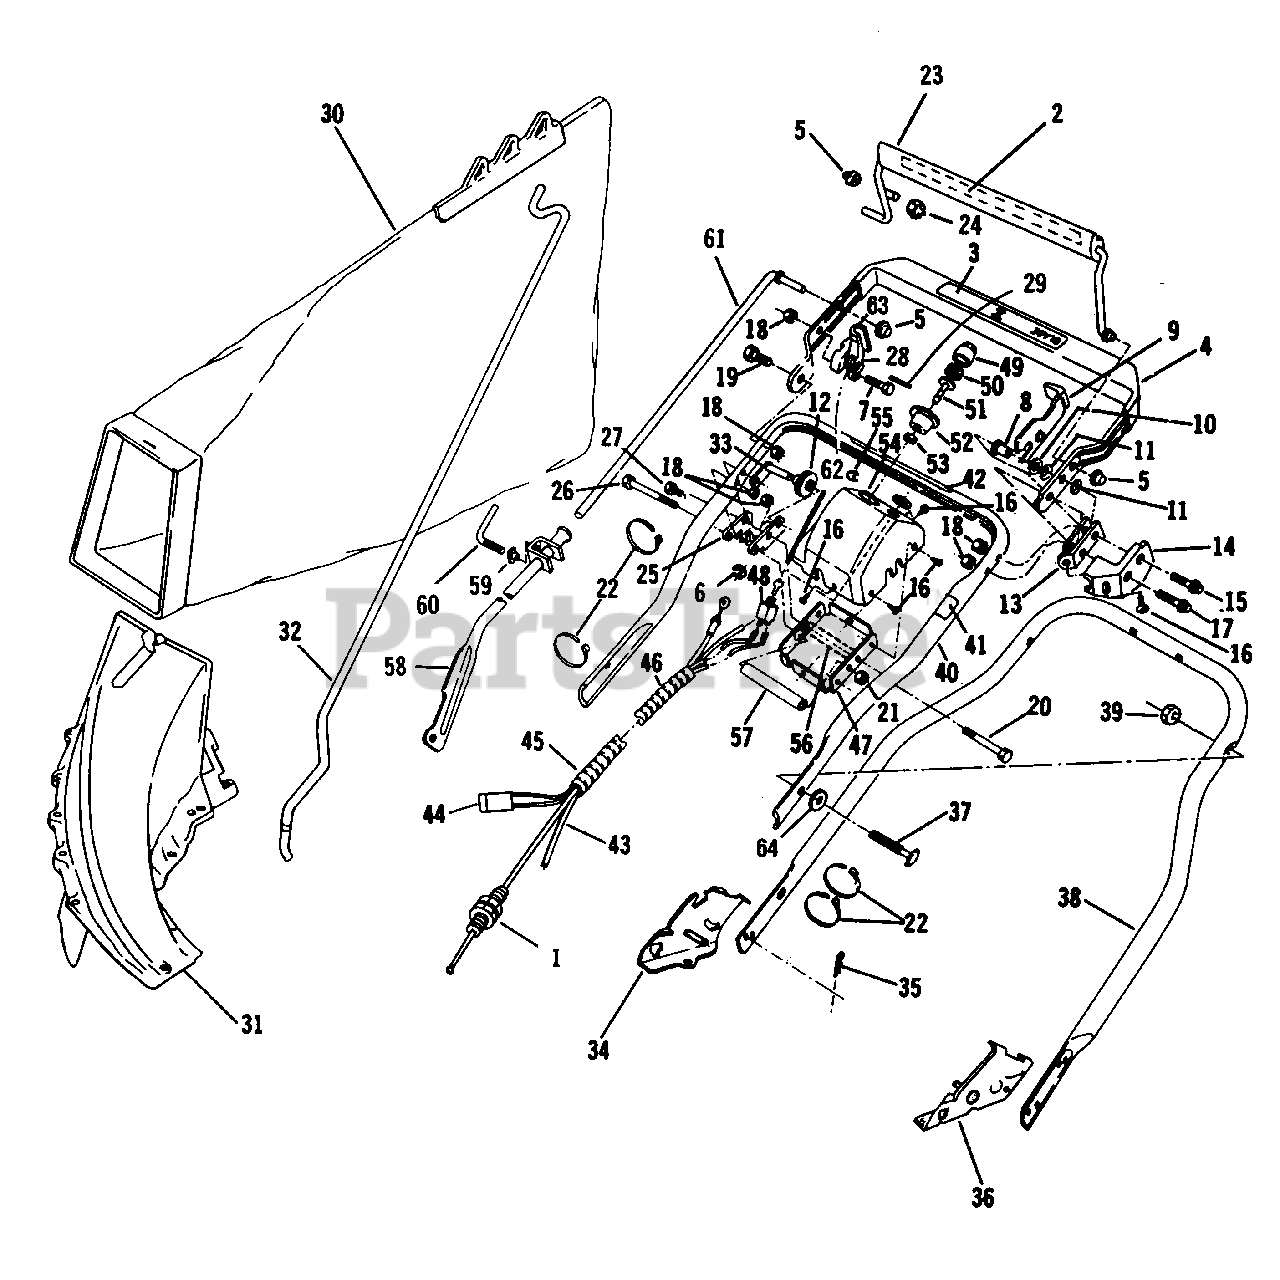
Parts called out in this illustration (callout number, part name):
1	Control Cable Assembly
2	Decal-Blade Control
3	Decal-Drive Control
4	Top Handle Assembly
5	Pushnut
6	Ring-Retainer
7	Bolt-Hex
8	Spacer-Flanged
9	Lever-Lockout
10	Washer-Plain
11	Washer-Spring
12	Pulley
13	Down-Stop
14	Guard-Lockout
15	Bolt-Shoulder
16	Screw
17	Bolt-Shoulder-L.H.
18	Locknut
19	Bolt-Shoulder-R.H.
20	Screw-Hex Hd. Cap
21	Nut-Hex Jam
22	Tie Strap
23	Control Lever and Nut Assembly
24	Nut-Acorn
25	Bracket-Clutch Cable
26	Screw
27	Screw-Clutch Cable Brkt.
28	Cam and Roll Pin Assembly
29	Roll Pin
30	Bag Assembly
31	Chute Assembly
32	Rod-Grass Bag
33	Pivot-Bracket Pulley
34	Bracket-Handle-R.H.
35	Hair Pin
36	Bracket-Handle-L.H.
37	Screw
38	Handle Section-Bottom
39	Nut
40	Handle Section-Center
41	Decal-Drive Lockout
42	Decal-Starting Inst.
43	Tubing-Primer
44	Wire Harness Assembly
45	Spiral Tubing
46	Spiral Tubing
47	Plate-Cover Assembly
48	Switch Assembly
49	Primer Bulb
50	Filter
51	Primer Base
52	Cup
53	Locknut
54	Cover
55	Decal
56	Spacer
57	Spacer
58	Control Lever Assembly
59	Nut-Control Lever Clamp
60	Lever-Rod Clamp
61	Rod-Control
62	Key Switch (2)
63	Cam
64	Washer
